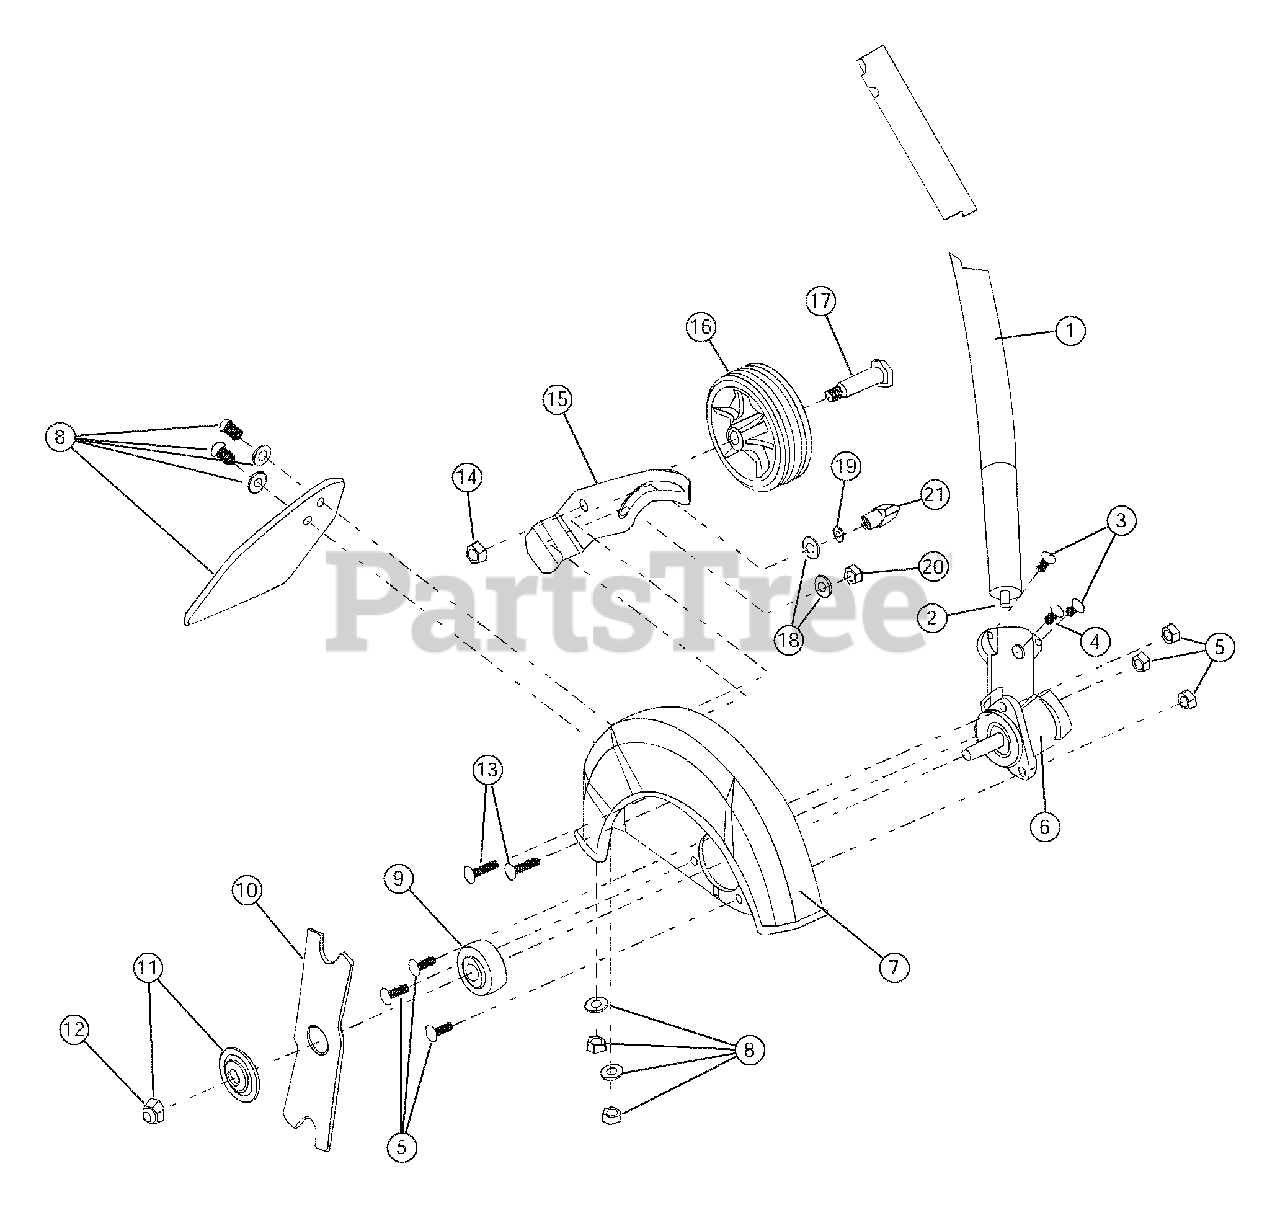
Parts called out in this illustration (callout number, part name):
1	Boom Assembly
2	Drive Shaft
3	Boom Mounting Hardware
4	Anti-Rotation Screw
5	Guard Mounting Hardware
6	Gearbox Assembly
7	Blade Guard
8	Deflector w/Hardware
9	Spacer
10	Blade
11	Blade Clamp Washer
12	Blade Retainer Nut
13	Wheel Bracket Mounting Bolt
14	Nut
15	Edger Guide
17	Shoulder Bolt
19	Washer
20	Nut
21	Edger Guide Knob
